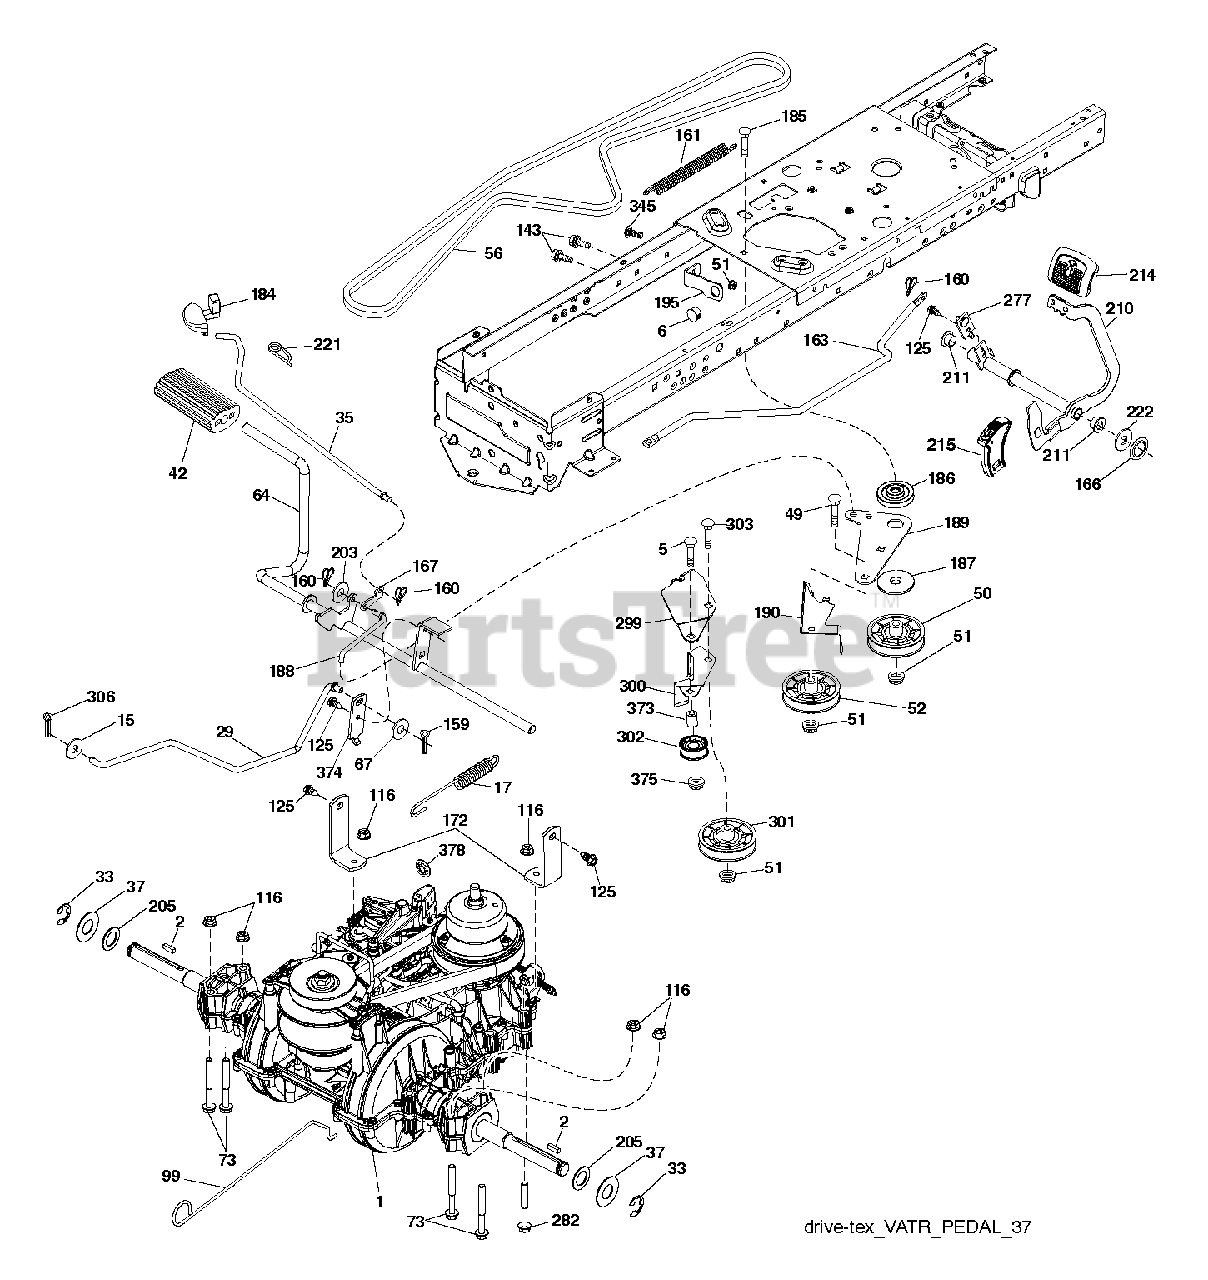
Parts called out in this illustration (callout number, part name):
2	SQUARE KEY
6	GROMMET T
15	WASHER
17	Brake Variator Spring
29	RB ROD.BRAKE.VARIATOR.SD2
33	E-RING LT
35	ROD .BRAKE. PARKING. GT. HUSQ.
37	WASHER.HARDENED
49	BOLT
50	IDLER.FLAT.910.OFFSET
51	NUT LOCK FLG 3/8-16 UNC
52	IDLER.V-GROOVE.910.OFFSET
56	BELT.DRIVE.MOWER.TEX.42"
64	SUBASM.SHAFT.PEDAL.BRAKE
67	WASHER
73	BOLT HEX 5/16-18 GR 5
99	ROD.BYPASS.VARIATOR.GEN2
116	NUT LOCK HEX FLANGE 5/16-18
125	SCREW
143	SCREW LT
159	COTTER PIN
160	RETAINER CLIP
161	SPRING, RETURN LT
163	ROD.CONTROL.PEDAL.VARIATOR
166	NUT.PUSH.625
167	LATCH.BRAKE.SPRING
172	STRAP.TORQUE.VARIATOR
186	SPACER.RETAINER
187	WASHER 12/32X2X10GA
188	LINK.CLUTCH.GROUND.DRIVE
189	BELLCRANK.GROUND.DRIVE.TEX.
190	KEEPER.BELLCRANK.DRIVE
195	BRACKET.BRAKE.BRAKE.VAR.SD
203	WASHER
210	WELDMENT.PEDAL.VARIATOR
211	BEARING.NYLON
214	PEDAL.FORWARD.PAD.TEX
215	CAP.PEDAL.REVERSE.VARIATOR
221	RETAINER.SPRING.CLIP.H
222	WASHER 21/32 X 1-1/4 X 10 GA.
277	SUBASM.LINK.ROCKER.PEDAL
282	BOLT HEX FLGHD 5/16-18X3 GR. 5
299	BRACKET.MOUNT.IDLERS
300	KEEPER.IDLERS.REAR.VARIATOR
301	PULLEY.IDLER.V-GROOVE
302	PULLEY.IDLER.FLAT.2"
303	BOLT CARRIAGE
306	PIN COTTER
374	ARM.CONTROL.BRAKE
375	LOCKNUT
378	NUT.PUSH.8MM
